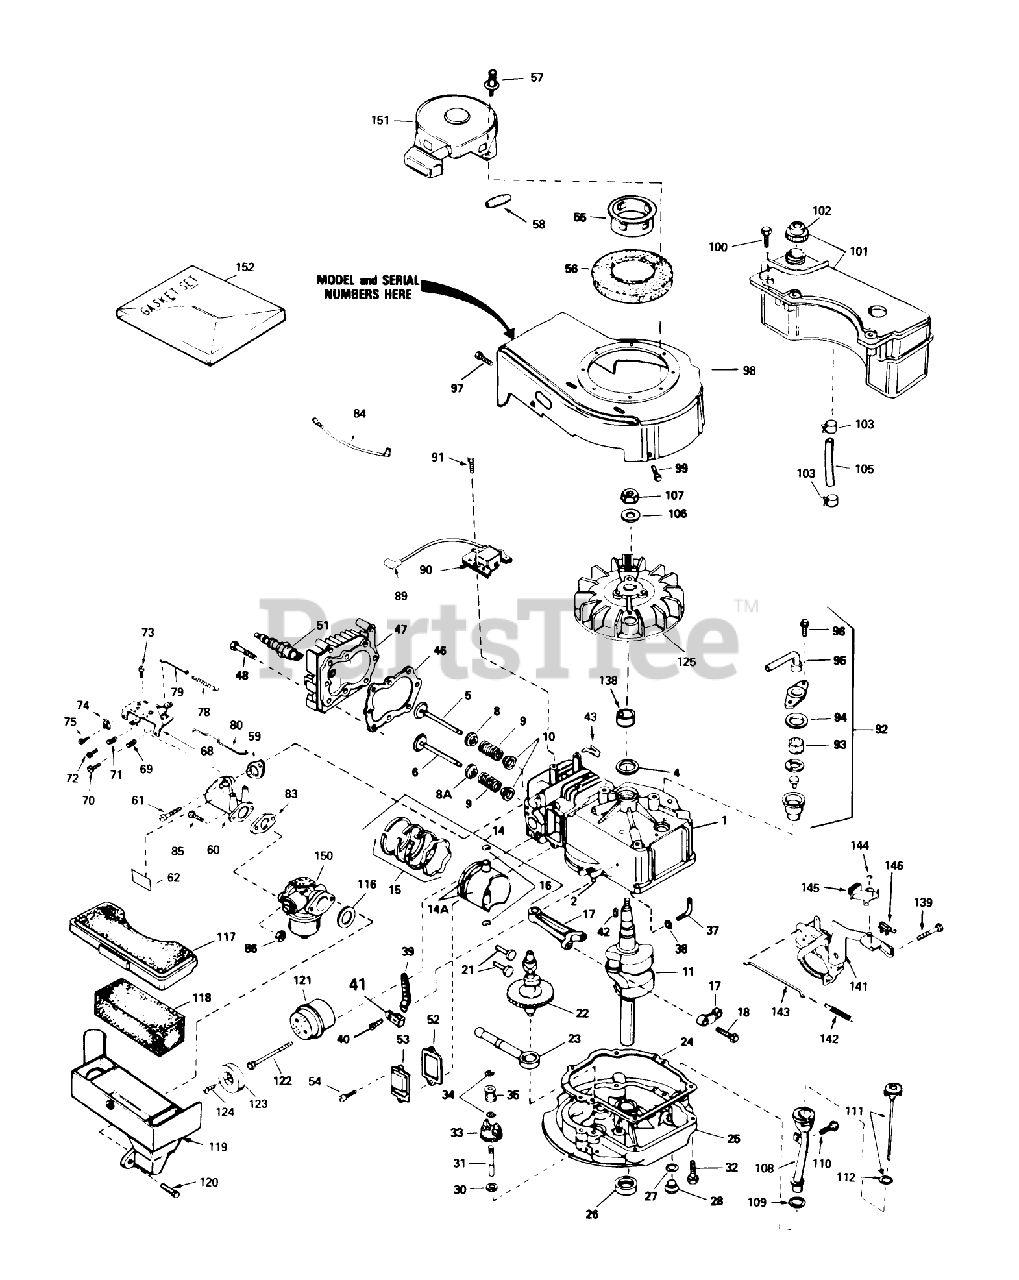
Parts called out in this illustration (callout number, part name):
1	Cylinder Assy. (Incl. #24)
2	Pin-Dowel
4	Seal-Oil
5	Valve, Intake (Std.) (Incl. Ref. #40)
5	Valve, Intake (1/32" oversize)(Incl. No. 40)
6	Valve, Exhaust (Std.)(Incl. No. 40)
6	Valve, Intake (1/32" oversize)(Incl. No. 40)
8	Seal Assy., Intake
8A	Cap-Upper Valve Spring
9	Spring-Valve
10	Cap-Valve, Spring
11	Crankshaft
14	Piston, Pin Ring Assy. (Std.) (Incl. Ref. #13A, 14 15)
14	Piston, Pin Ring Assy. (.010 oversize) (Incl. Ref. #13A, 14 15)
14	Piston, Pin Ring Assy. (.020 oversize) (Incl. Ref. #13A, 14 15)
14A	Piston Pin Assy. (Incl . Ref. . #14) (Std.)
14A	Piston Pin Assy. (Incl. Ref. #14) (.010 Oversize)
14A	Piston Pin Assy. (.020 oversize) (Incl. Ref. #14)
15	Ring Set (Std.)
15	Ring Set (.020" OS)
15	Ring Set (.010" OS)
16	Ring-Retaining, Piston Pin
17	Rod Assy., Connecting (Incl. Ref. #17)
18	Bolt-Rod, Connecting
21	Lifter-Valve
22	Camshaft(Mech.Comp. Release)
23	Oil Pump ASM
24	Gasket
25	Flange Assy.-Mounting (Incl. Ref. #26, 27, 28 31)
26	Seal Oil
27	Gasket-Oil Drain
28	Plug Oil Drain
30	Washer-Flat
31	Shaft-Governor
32	Screw (1/4-20 x 1-1/4)
33	Governor Gear ASM
34	Ring-Retaining
35	Spool-Governor
37	Rod, Governor (Incl. No. 36)
38	Washer-Flat
39	Governor Lever
40	Screw
41	Clamp-Lever, Governor
42	Key-Flywheel
43	Clip-Wire
46	63573 GIL 42 SNWTHW
47	Head-Cylinder
48	Screw (5/16-18x1-1/2)
51	Plug, Spark (Autolite 458, Champion J-19LM or equiv.)
52	Gasket-Breather
53	Cover-Valve
54	Screw
55	Cup-Starter
56	Screen-Starter
57	Pop Rivet (Can be purchased locally)
58	Retainer-Starter Rope
59	Gasket-Intake
60	Pipe-Intake (Incl. Ref. #59)
61	Screw (1/4-20 x 1)
62	Decal-Primer
68	Control Assy.-Remote Speed (Incl. Ref. #69 thru 72 76)
69	61709/GIL1515A/95-5
70	Screw
71	Spring-Compression
72	Screw
73	Screw (10-24 x 9/16)
74	Conduit
75	Screw (10-32 x 3/8)
78	Spring Governor
79	2035A67 ADD.ASSEMBL
80	Link-Throttle
83	Gasket
84	Ground Wire
86	Nut and Lock Washer (1/4-28)
89	Cover-Spark Plug
90	Solid State
91	Screw
92	Breather Assy. (Incl. Ref. #46 thru 51)
93	Element-Breather
94	Gasket-Breather
95	Tube, Breaker
96	Screw (10-24 x 9/16)
97	Screw (10-24 x 9/16)
98	Housing-Blower
99	Screw (1/4-20 x 1/2)
100	Screw (10-32 x 35/64)
101	Tank Assembly-Fuel (Incl. Ref. #102)
102	Cap-Fuel
103	Clamp-Line, Fuel
105	Line-Fuel
106	Washer-Belleville
107	Nut-Flywheel
108	Tube-Oil Fill
109	Gasket
110	Screw (10-32 x 1/2)
111	Dipstick-Oil (Incl. Ref. #112)
112	O-Ring
116	Gasket-Cleaner, Air
117	Cover Air Cleaner
118	Filter-Air Cleaner
119	Body Air cleaner
120	Screw
121	Muffler (Incl. Ref. #122)
122	Screw
123	Cover-Muffler
124	Screw
125	Flywheel
138	Spacer
139	Screw (1/4-20 x 3/8)
141	Bracket Assy.
142	Spring-Extension
143	Link-Control
144	Ring-Retaining
145	Lever-Brake
146	Terminal
150	Carburetor (Incl. Ref. #83)
151	tarter-Rewind
152	Gasket Set
